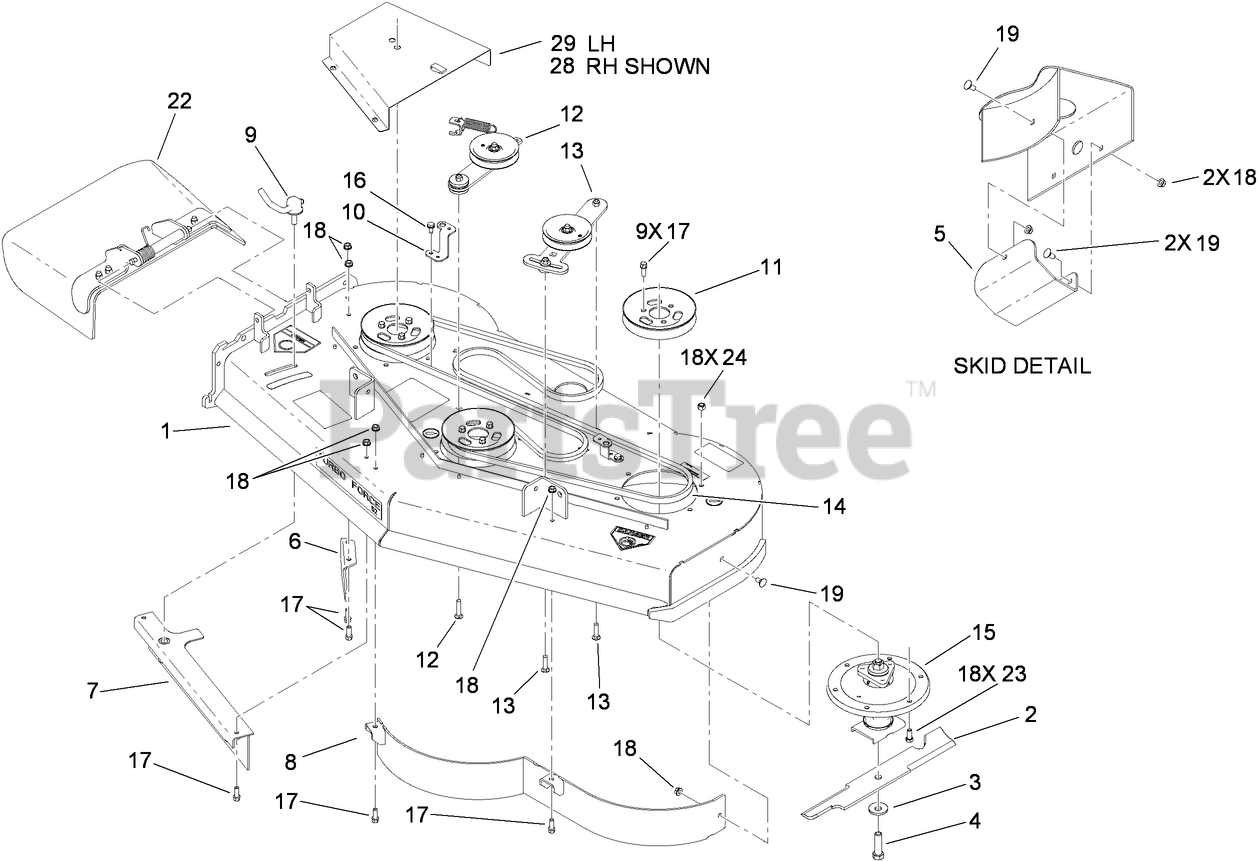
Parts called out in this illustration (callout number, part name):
1	DECK ASM
2	BLADE-18IN, HI FLOW
3	Washer-Blade Bolt, Heavy
4	Screw-Cap
6	BAFFLE-DISCHARGE
8	BAFFLE-52 INCH
9	LEVER ASM
10	BRACKET-COVER, TALL
11	Pulley
12	SPRING IDLER ASM
13	IDLER ADJUST ASM
14	BELT-V
15	SPINDLE ASM
16	SCREW-HWHTF
17	SCREW-HWH
18	NUT-HHF, WHIZ
19	SCREW-CARR
22	DEFLECTOR ASM
23	SCREW-HH
24	NUT-LOCK, NI
28	LH BELT COVER ASM
29	RH BELT COVER ASM
